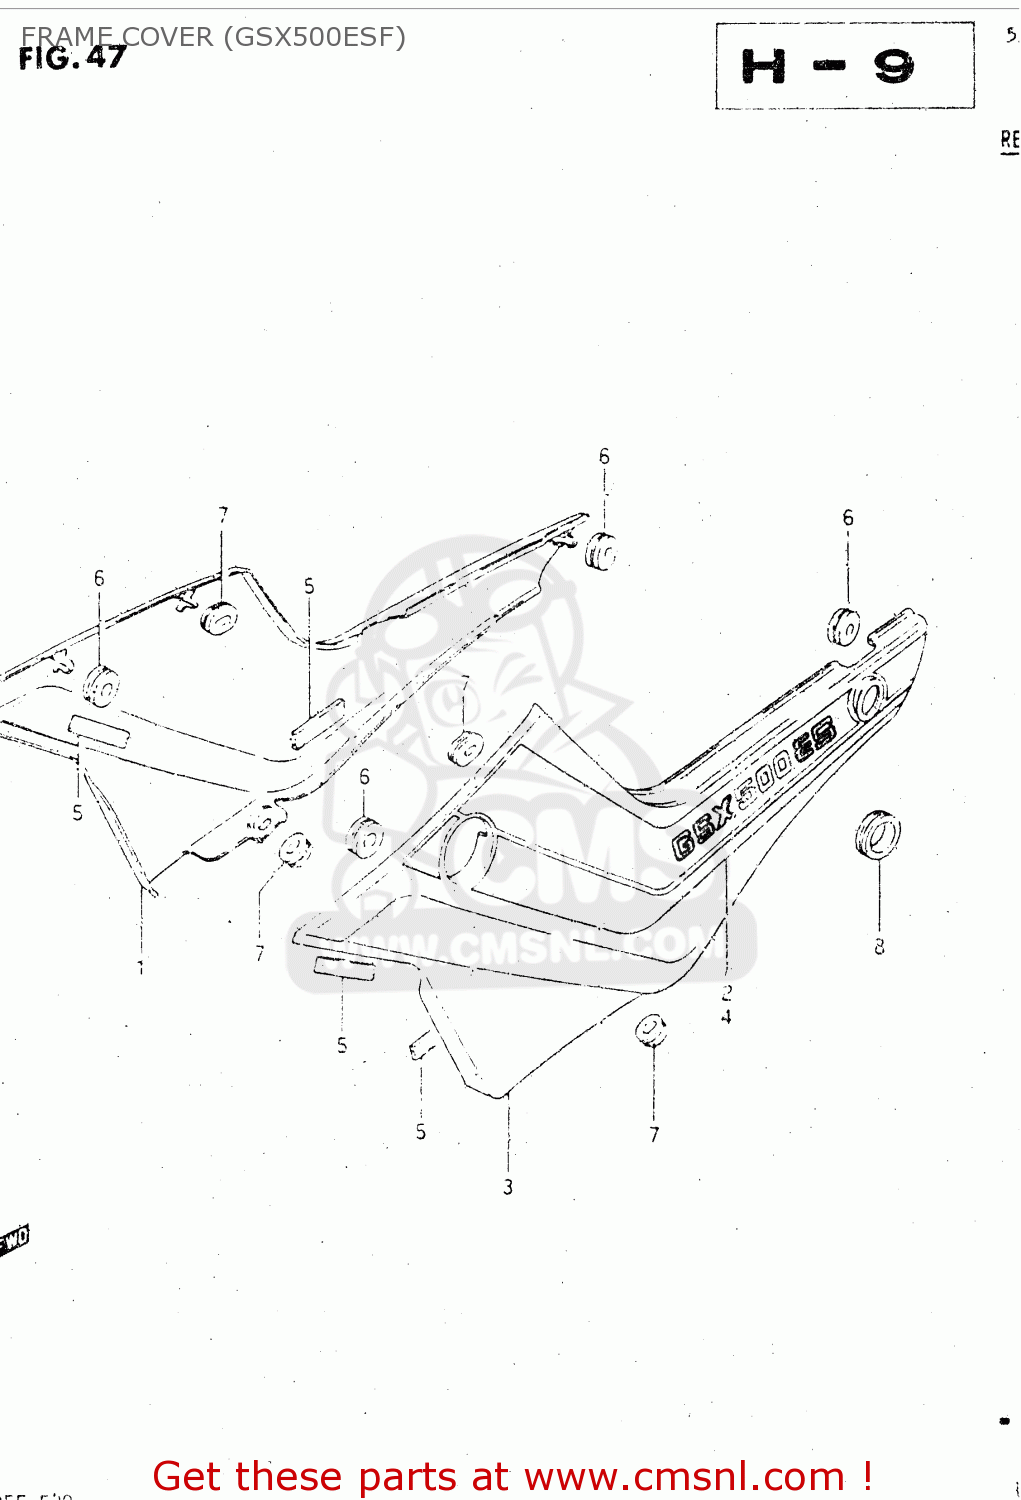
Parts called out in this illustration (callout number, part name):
1	COVER, FRAME RH (WHITE)
2	TAPE SET, FRAME COVER RH
3	COVER, FRAME LH (WHITE)
4	TAPE SET, FRAME COVER LH
5	RUBBER,FRAME COVER
6	CUSHION
7	CUSHION
8	GROMMET,SEAT LOCK HOLE
